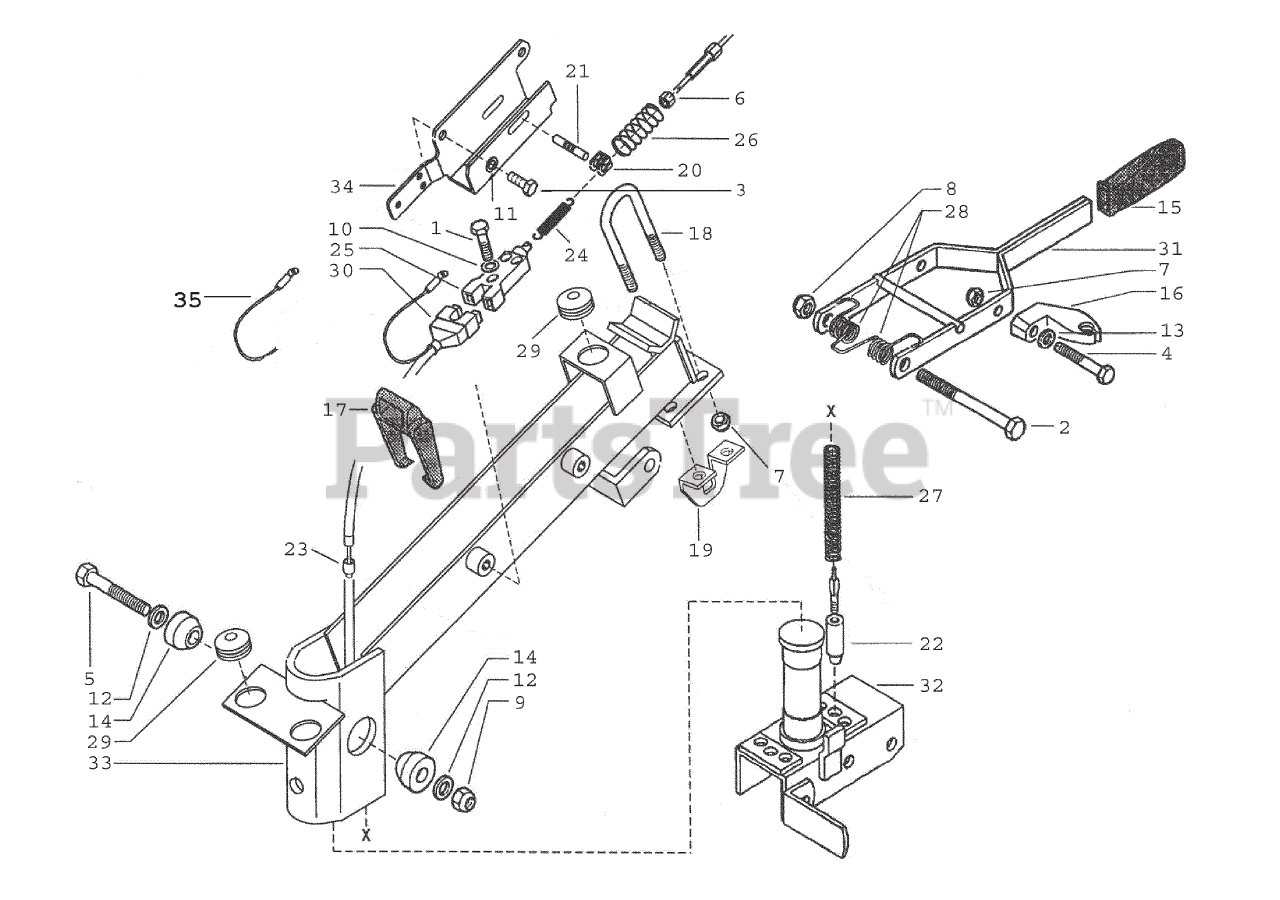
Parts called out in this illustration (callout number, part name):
1	CAP SCREW, M4.7X25
2	CAP SCREW, M10X110
3	CAP SCREW, MX20
4	CAP SCREW, M8X35
5	CAP SCREW, M12X80
6	NUT, M8
7	LOCK NUT, M8
8	LOCK NUT, M10
9	LOCK NUT, M12 DEFORMED
10	WASHER, FLAT, M4
11	WASHER, SUPER M8
12	SPRING WASHER
13	WASHER LOCK B 8.4
14	WEDGE
16	SUPPORT, CONTROL ROD
17	CABLE GUIDE
18	U BOLT
19	BRACKET
20	MOTOR STOP FORK
21	SPRING CHECK PIN
23	SHEATH END
24	SPRING, STOP
25	STOP SWITCH
26	CHECK SPRING, MOTOR STOP
27	SPRING, STEERING COLUMN
28	HANDLEBAR RELEASE SPRING
29	SUPPORT CAP
30	MOTOR STOP WIRING
31	LEVER, HANDLEBAR SELECTION
32	SUPPORT
33	STEERING COLUMN
34	SUPPORT, ENGINE STOP
35	GROUND WIRE, FOR S/N 794196+
